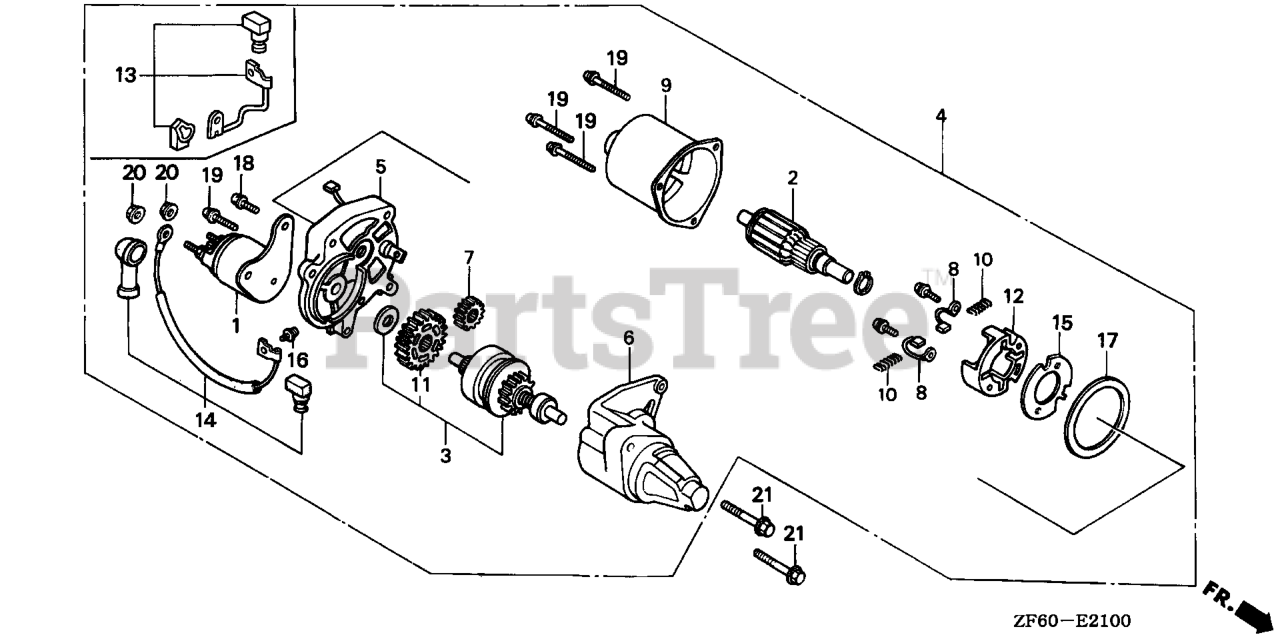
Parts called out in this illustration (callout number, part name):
1	CONTACTOR ASSY.
2	ARMATURE
3	CLUTCH, OVERRUNNING
4	STARTER MOTOR UNIT
5	BRACKET, CENTER
6	BRACKET, FR.
7	GEAR, DRIVE PINION
8	BRUSH
9	YOKE
10	SPRING, BRUSH RETURN
11	GEAR, REDUCTION
12	HOLDER, BRUSH
14	WIRE, WATER COVER
15	INSULATOR
16	SCREW-WASHER (4X6)
17	GASKET
18	BOLT-WASHER (5X14)
18	SCREW-WASHER (5X14)
19	SCREW-WASHER (5X3)
20	NUT-WASHER (6MM)
21	BOLT, FLANGE (8X35)
